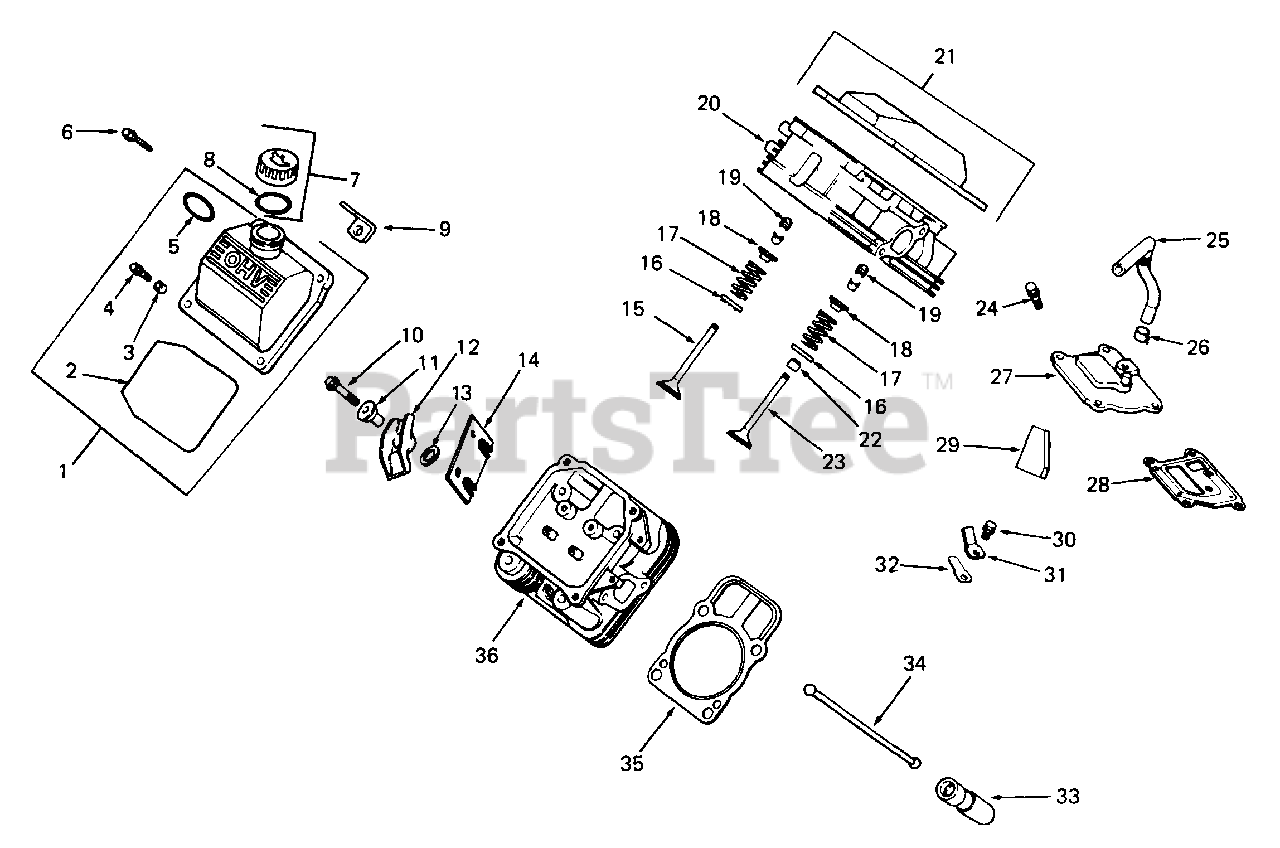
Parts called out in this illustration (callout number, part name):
1	Kit, Valve Cover w/Oil Fill
2	O-Ring, Cover
4	Screw, M6 X 1.0 X 30
5	O-Ring, Filler Neck
6	Screw, M10 X 1.5 X 91
7	Kit, Oil Fill Cap
8	O-Ring, Oil Fill Cap
9	Strap, Lifting
10	Screw, M6 X 1.0 X 34
11	Pivot, Rocker Arm
13	Washer, Flat
14	Plate, Guide
15	Valve, Exhaust, Std
16	Retainer, Spring
17	Spring, Valve
18	Cap, Valve Spring
19	Lock, Retainer
20	Head Assy, Cylinder #1
21	Kit, Valve Cover
22	Seal, Valve Stem
23	Valve, Intake, Std
24	Screw, M6 X 1.0 X 20
25	Hose, Breather
26	Clamp, Hose
27	Cover, Breather
28	Gasket, Breather
29	Filter, Breather
30	Screw, Breather Reed Retainer, M5 X 0.8 X 10
31	Retainer, Breather Reed
32	Reed, Breather
33	Lifter, Valve
34	Rod, Push
35	Gasket, Cylinder Head
36	Head Assy, Cylinder #2
